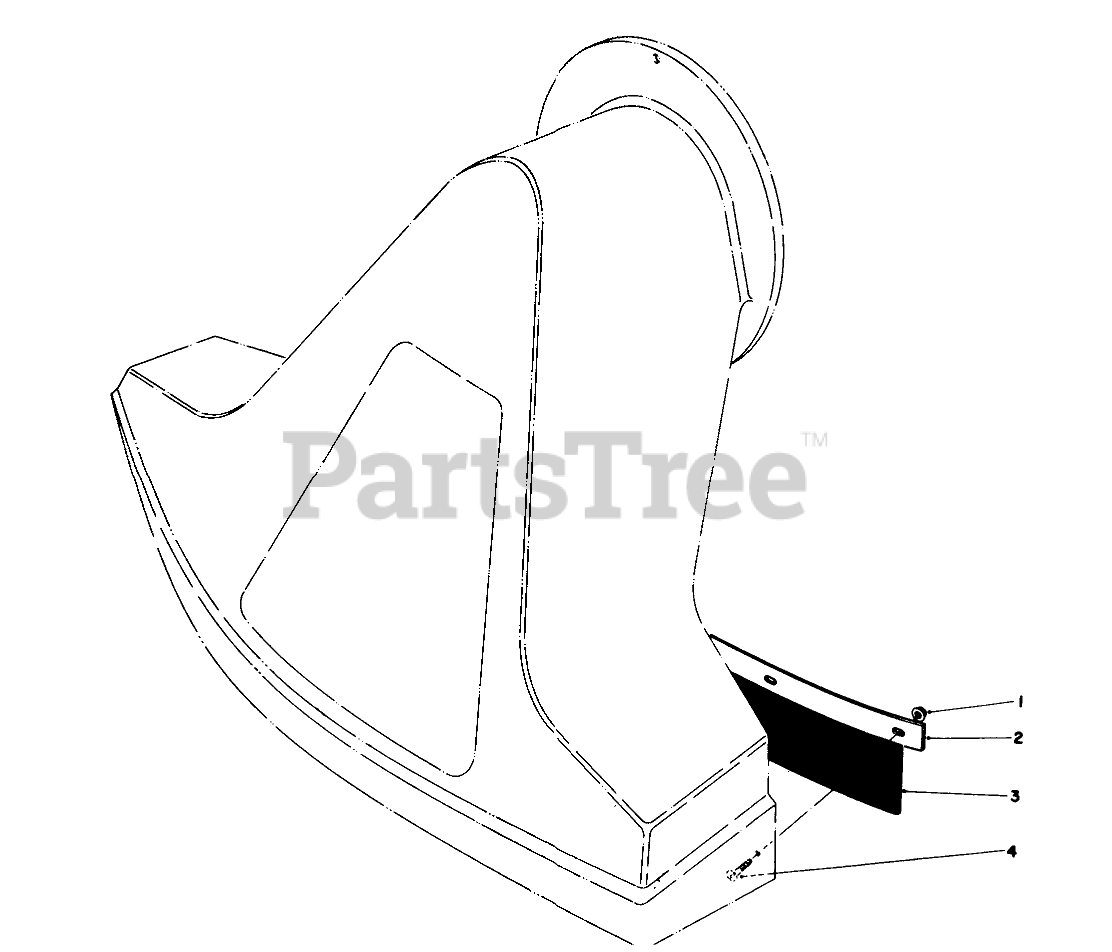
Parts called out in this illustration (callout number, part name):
1	NUT-LOCK, FLANGE
2	Clamp-Flap
3	FLAP-RUBBER
4	10-24 X 5/8 PAN HD MS
